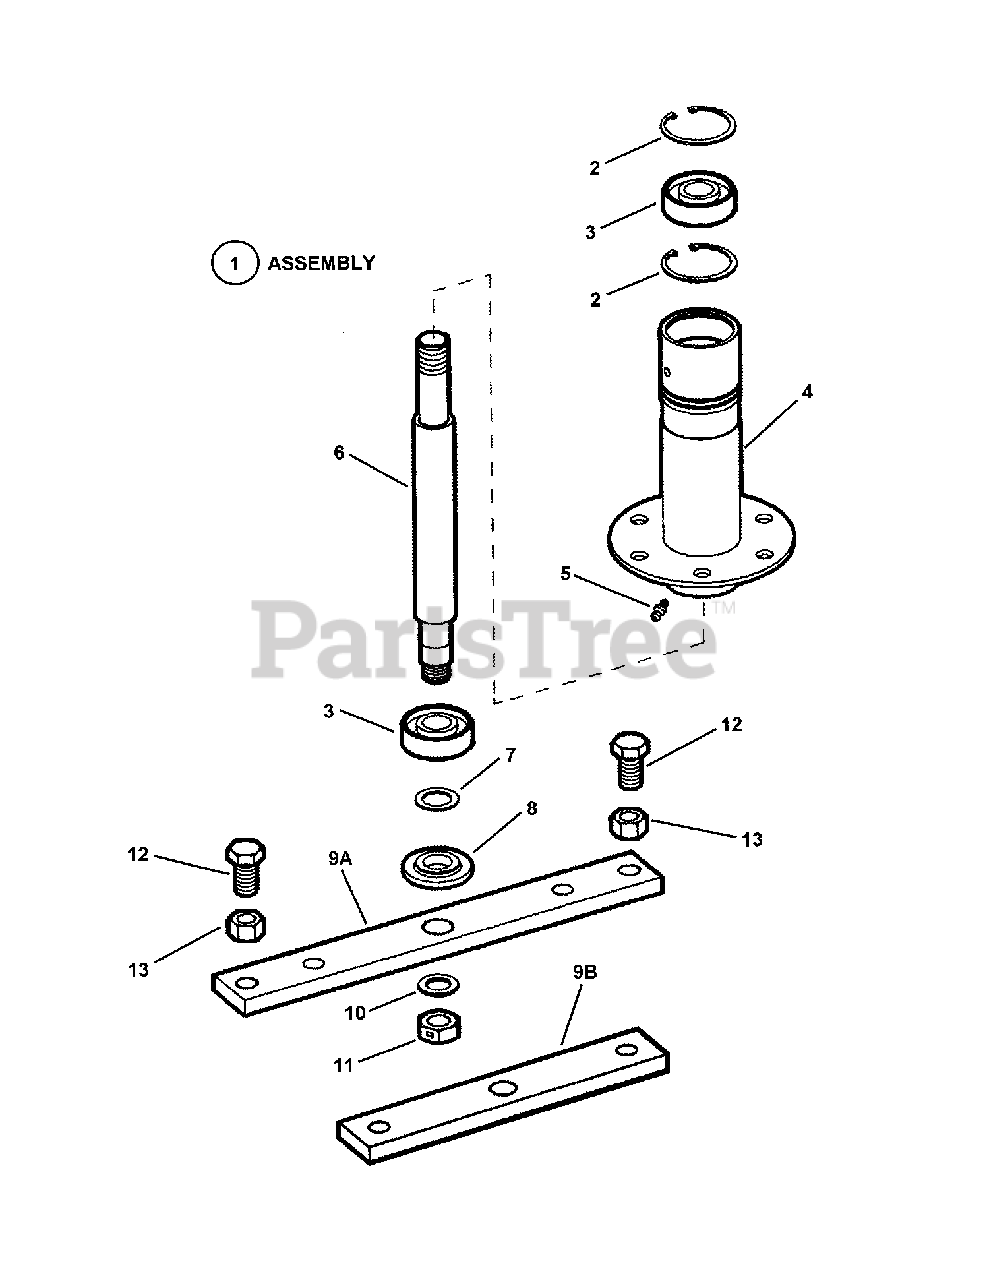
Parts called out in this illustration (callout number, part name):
1	ASSEMBLY, Spindle Housing (Incl. items 2 thru 9A & 10 thru 13)
1	ASSEMBLY, Spindle Housing (Incl. items 2 thru 8 & 9B thru 11)
2	RING, 1.85" Internal Retaining
3	BEARING, Spindle
4	WELDMENT, Spindle Housing (Incl. item #5)
5	LUBE FITTING, 3/16" Press-In
6	SPINDLE, Rider (10.327" overall length)
7	WASHER, .77 x 1.13 x .06 Flat
8	WASHER, Spindle
9A	HOLDER, Blade
9B	HOLDER, Blade
10	SPACER, Blade Centering
11	NUT, 5/8-18 Hex Center Lock Jam
12	SCREW, 1/2-20 x 1-1/4" Hex Head Cap, GR 5
13	NUT, 1/2-20 Hex, GR 5 or B
